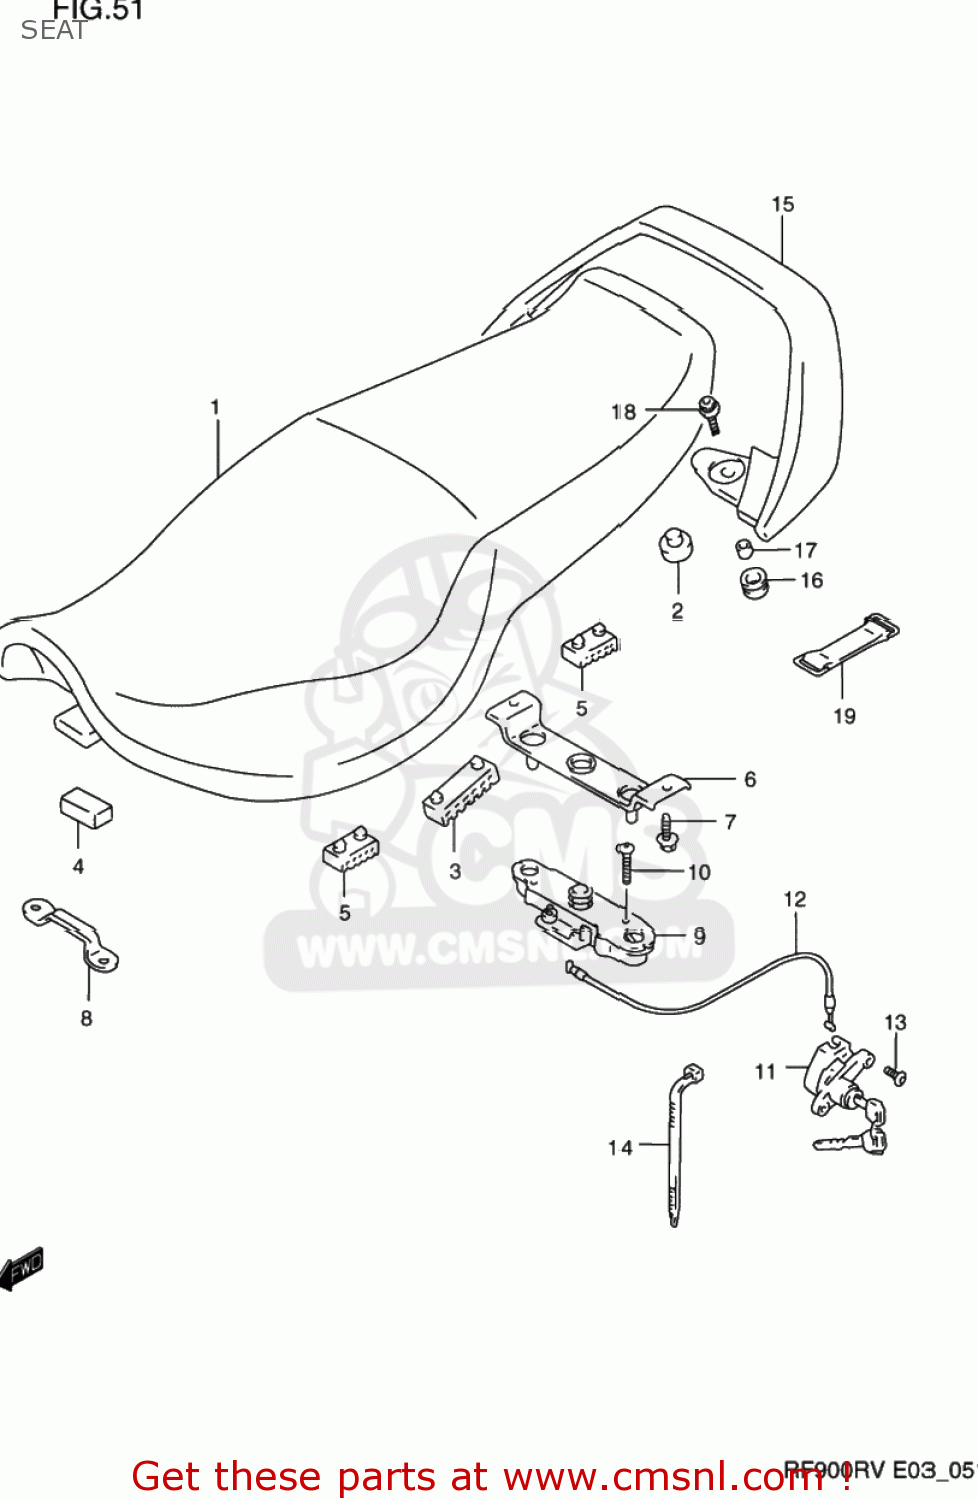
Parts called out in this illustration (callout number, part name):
1	SEAT ASSY
2	CUSHION
3	CUSHION,SEAT
4	CUSHION,FR(20X40X15)
5	CUSHION,SEAT(40X20X15)
6	STRIKER,SEAT LOCK
7	BOLT
8	PLATE,SEAT FR HOOK
9	LOCK ASSY,SEAT STRIKER
10	SCREW 6X30
11	LOCK SET,SEAT
12	CABLE,SEAT LOCK
13	SCREW(6X12)
14	CLAMP L:165
15	HANDLE,PILLION RIDER
16	CUSHION
17	WASHER(8.5X28X1.6)
18	BOLT
19	BAND
